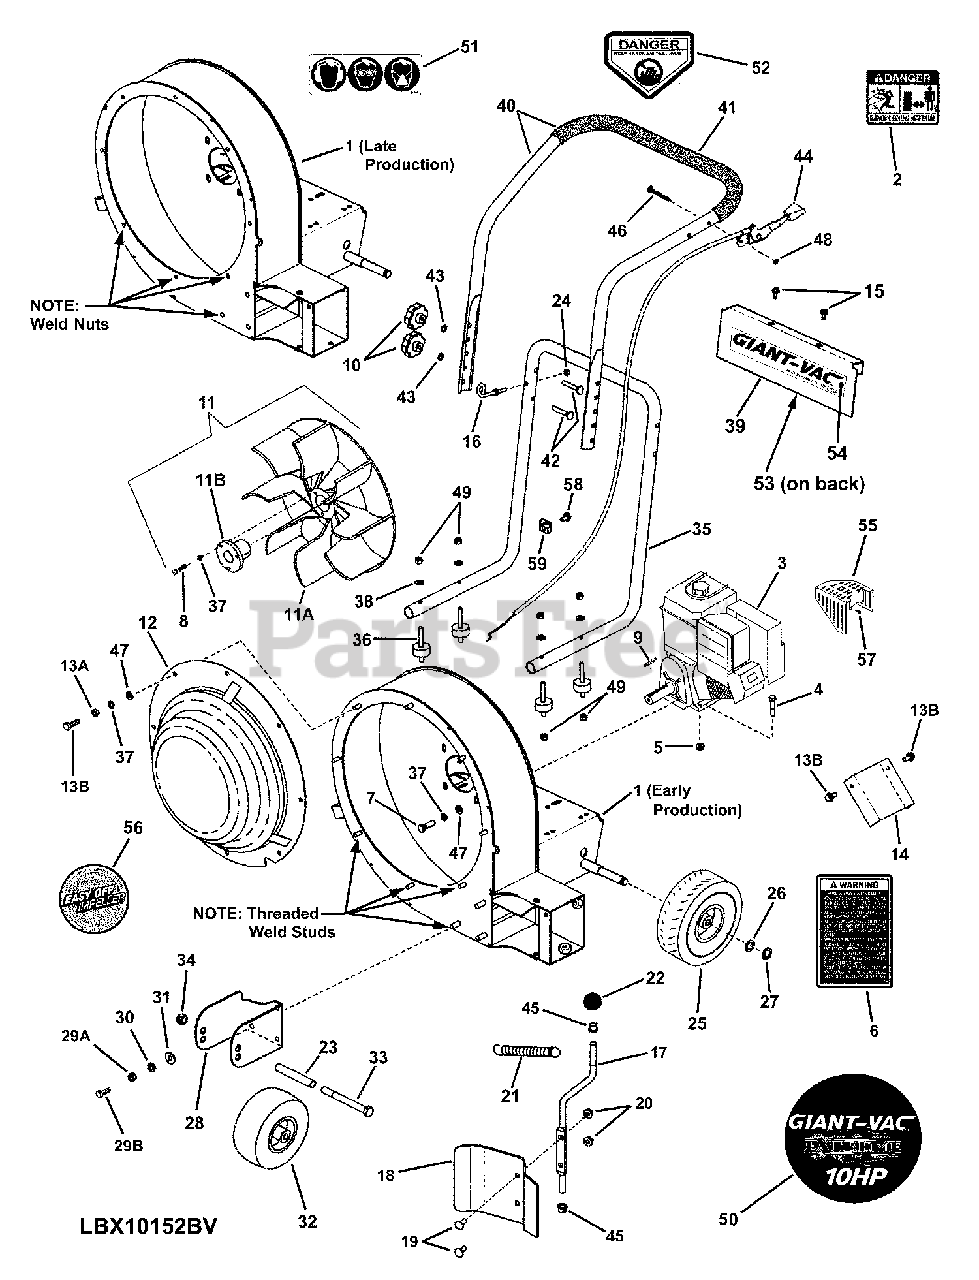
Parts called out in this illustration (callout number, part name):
1	WELDMENT, Housing- Extreme Blower
2	DECAL, Thrown Objects, Large
3	* ENGINE, B&S 10HP Mod 205412-0121-E1
4	SCREW, 5/16-18 x 1-1/2 Hex Head Cap, GR 5
5	NUT, 5/16-18 Hex Flange Lock, GR 5
6	DECAL, Warning - Leaf Blower
7	SCREW, 5/16-24 x 1" Hex Head Cap, GR 5
8	SCREW, 5/16-18 x 1-1/4", Hex Head Cap, GR 5
9	KEY, 1/4" Square x 1-7/16"
10	KNOB, Fluted (5/16-18 thread)
11	ASSEMBLY, 15" 9 Blade Impeller
11A	IMPELLER, Cast, 15" O.D.
11B	HUB, Taper-Lok, Type 1
12	WELDMENT, Intake Baffle - Extreme
13A	NUT, 5/16-18 Hex, GR 5 or B
13B	SCREW, 5/16-18 x 3/4" Hex Head Cap, GR 5
14	DEFLECTOR, Side Air
15	SCREW, 5/16-18 x 5/8" Hex Washer Self-Tap
16	GUIDE, Rope (1/4-20 thread)
17	ROD, Door Front/Side Discharge
18	DOOR, Forward Air Control
19	SCREW, 1/4-20 x 3/4" Short Sq. Neck Carriage
20	NUT, 1/4-20 Hex Flange Lock, GR 5
21	SPRING, Extension
22	KNOB, Ball - 3/8-16 Metal Insert
23	SLEEVE, Axle
24	NUT, 1/4-20 Hex Center Lock, GR 5 or B
25	ASSY., Wheel & Tire Sawtooth 4.10/3.50-4
25	ASSY., Wheel & Tire (Flatfree) 4.10/3.50-4
26	WASHER, .64 x .99 x .05 Flat
27	RING, External Retaining
28	BRACKET, Front Wheel Mounting
29A	NUT, 3/8-16 Hex, GR 5 or B
29B	SCREW, 3/8-16 x 1" Hex Head Cap, GR 5
30	WASHER, 3/8" Split Lock
31	WASHER, 3/8" Flat
32	ASSY., Tire & Wheel 9 x 3.50-4 Smooth
32	ASSY., Tire & Wheel 9 x 3.50-4 "Flatfree"
32A	*** RIM, One-Piece Steel, Gray
32B	*** TIRE, 9 x 3.50-4, 4 Ply, Smooth
32C	*** BEARING, Roller
32D	*** BALL BEARING, Flanged
32E	*** VALVE, Air
32F	*** GREASE FITTING, 45-Degree
33	BOLT, 1/2-13 x 5" Hex Head Cap
34	NUT, 1/2-13 Hex Center Lock, GR 5
35	HANDLE, Lower Folding - Wide - Blower
36	MOUNT, Vibration (5/16-18, both ends)
37	WASHER, 5/16" Split Lock
38	WASHER, 5/16" Curved
39	DASH PANEL, Blower - Wide
40	ASSY, Upper Handle & Grip
41	GRIP, 1.0 x 21-1/2" Foam
42	BOLT, 5/16-18 x 2", Curved Head Sq. Neck
43	WASHER, 5/16" Internal Tooth Lock
44	THROTTLE CONTROL, (35/1.62) Briggs
45	BEARING, 3/8" Clip
46	SCREW, 1/4-20 x 2" Hex Head Cap, GR 5
47	WASHER, .34 x .69 x .08 Flat
48	NUT,1/4-20 Hex Nyloc
49	NUT, 5/16-18 Hex Nyloc
50	DECAL, Giant-Vac, 10HP Extreme
51	DECAL, Personal Protection
52	DECAL, Danger, Cut Finger
53	DECAL, GIANT-VAC (Small)
54	DECAL, GIANT VAC
55	HEAT SHIELD, B&S 9 & 10 HP Intek
56	DECAL, Easy Off Impeller
57	SCREW, #8-18 x 1/2" Hex Head Sheet Metal
58	SCREW, Casing Clamp - B&S Intek Engine
59	CASING CLAMP, B&S Intek Engine
